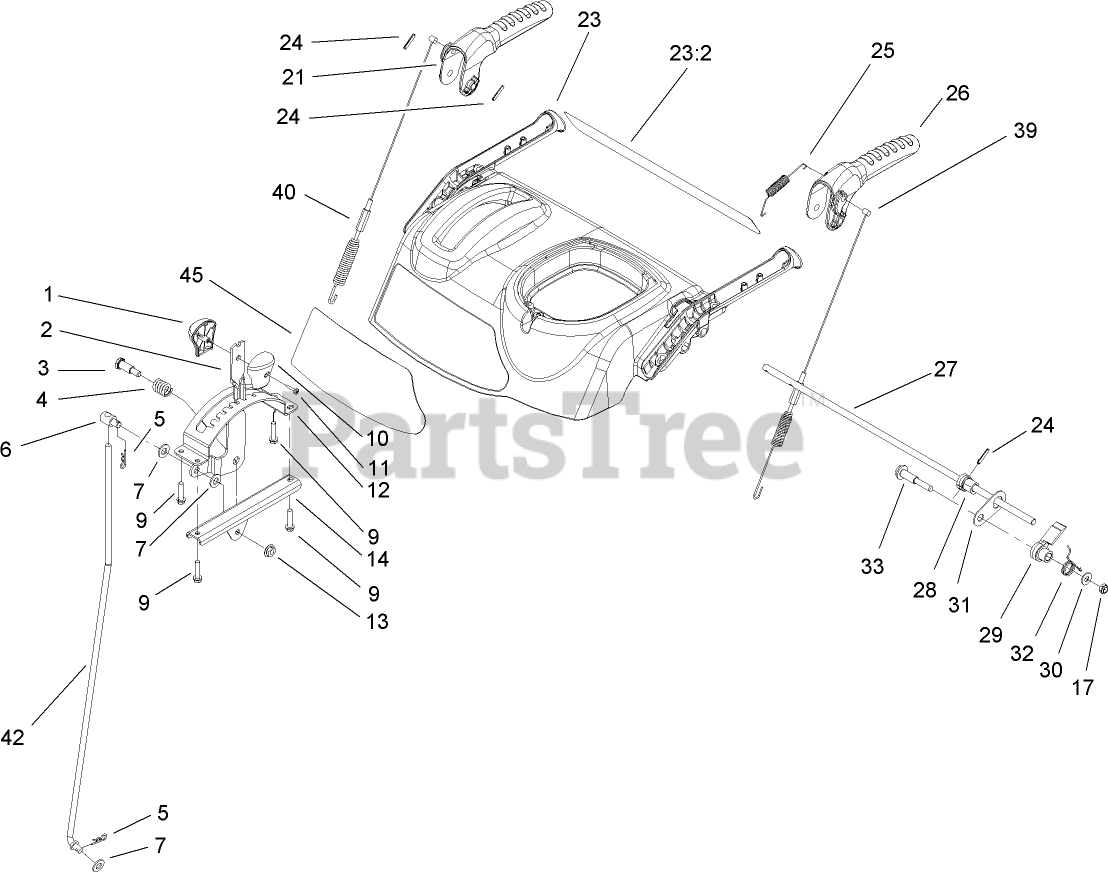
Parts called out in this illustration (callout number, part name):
1	KNOB-SHIFT, RH
2	SELECTOR-SPEED
3	SCREW-SHOULDER
4	SPRING-COMPRESSION
5	PIN-COTTER
6	TRUNNION-ROD
7	WASHER-FLAT
9	SCREW-PLASTITE
10	KNOB-SHIFT, LH
11	SCREW-PPH
12	GUIDE-SELECTOR, SPEED
13	NUT-HF
14	MOUNT-SELECTOR, SPEED
17	NUT-LOCK, NI
21	LEVER-AUGER
23	CONTROL PANEL ASM
23:2	DECAL-PANEL, CONTROL
24	PIN-SPRING
25	SPRING-TENSION
26	LEVER-TRACTION
27	ROD-LOCKOUT
28	CAM-LOCKOUT
29	LATCH-LOCKOUT
30	WASHER-FLAT
31	LINK-LOCKOUT
32	SPRING-TORSION
33	SCREW-SHOULDER
39	CABLE-TRACTION
40	CABLE-AUGER
42	ROD-SHIFT
45	DECAL-PANEL, CONTROL
